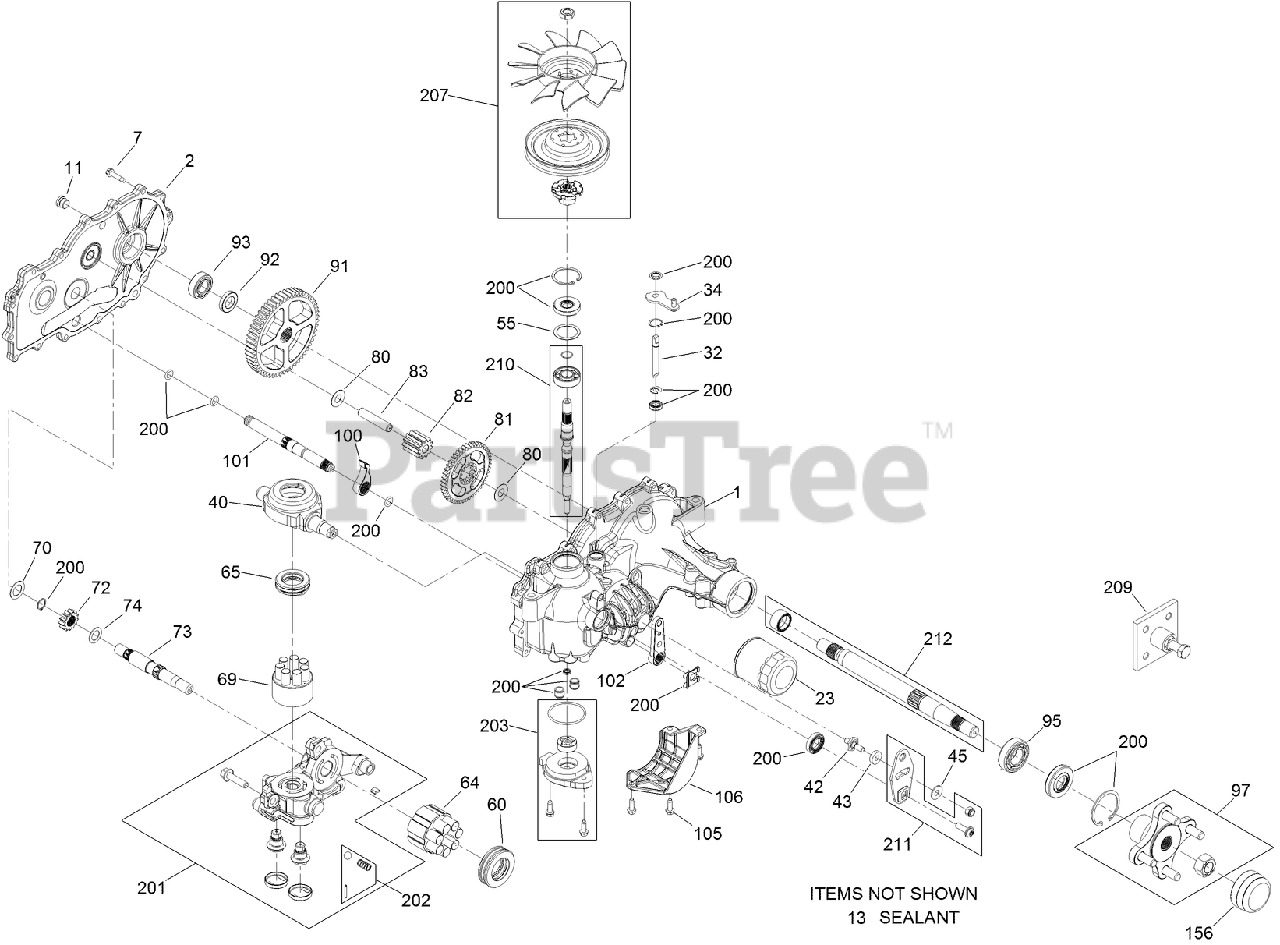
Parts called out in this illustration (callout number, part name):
1	LH MAIN HOUSING KIT
2	LH SIDE COVER KIT
7	SCREW-HHF
11	PLUG-THREAD, STRAIGHT
13	SEALANT
23	ELEMENT-OIL FILTER, HYD
32	ROD-BYPASS
34	ARM-BYPASS
40	SWASHPLATE-TRUNNION
43	PUCK-FRICTION
45	WASHER
55	SPACER
60	BEARING-THRUST
64	MOTOR CYLINDER BLOCK KIT
65	BEARING-THRUST
69	PUMP BLOCK ASM
70	WASHER-FLAT
72	GEAR-13T
73	SHAFT-MOTOR
74	WASHER
80	WASHER
81	GEAR-46T
82	GEAR-11T
83	PIN-JACKSHAFT
91	GEAR-54T
92	SPACER
93	BEARING-BALL
95	BEARING-BALL
97	HUB KIT
100	PAWL-BRAKE
101	SHAFT-BRAKE, INBOARD
102	HANDLE-BRAKE
106	GUARD-FILTER, LH
156	COVER-NUT, AXLE
200	SEAL KIT
201	LH CENTER SECTION CHARGE KIT
202	CHARGE RELIEF KIT
203	CHARGE KIT
207	FAN AND PULLEY KIT
209	PULLER-HUB, 4 BOLT
210	INPUT SHAFT KIT
211	CONTROL ARM KIT
212	AXLE SHAFT KIT
